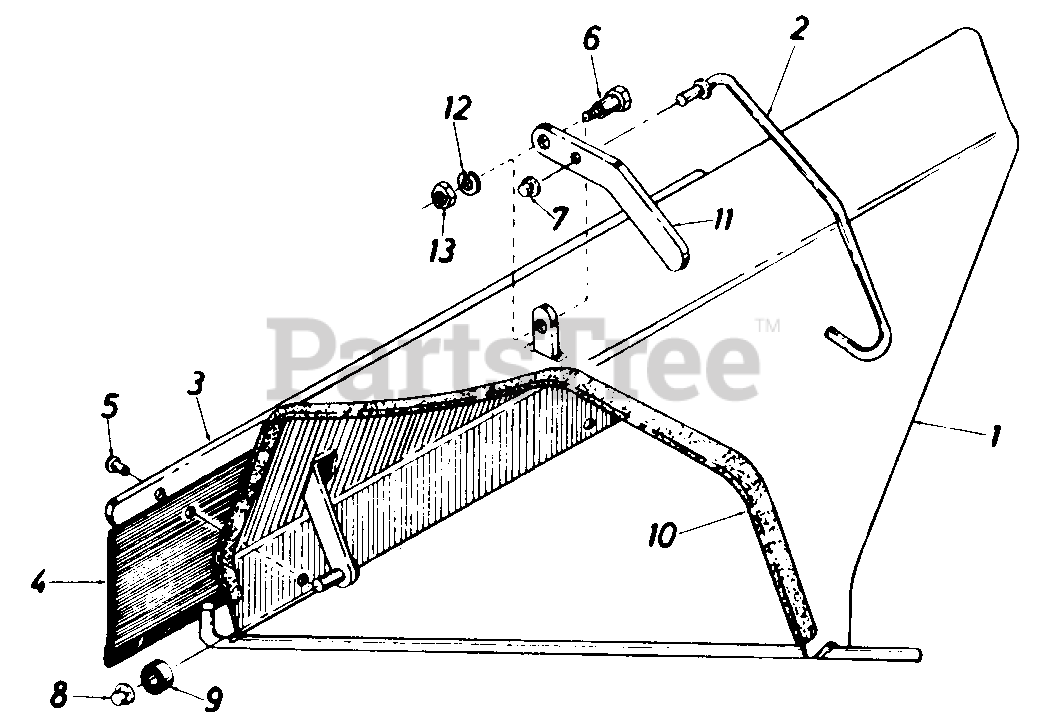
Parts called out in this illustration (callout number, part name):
1	Deflector Ass'y.
2	Hook Ass'y.
3	Retaining Strip
5	Rivet
6	Shld. Bolt.375" Dia. x .171 Lg.
7	Palnut 1/4" Rod
8	Palnut 3/8" Rod
9	Roller
10	Moulding
11	Latch Arm
12	L-Wash. 1/4" I.D.*
13	Hex Nut 1/4-20 Thd. *
